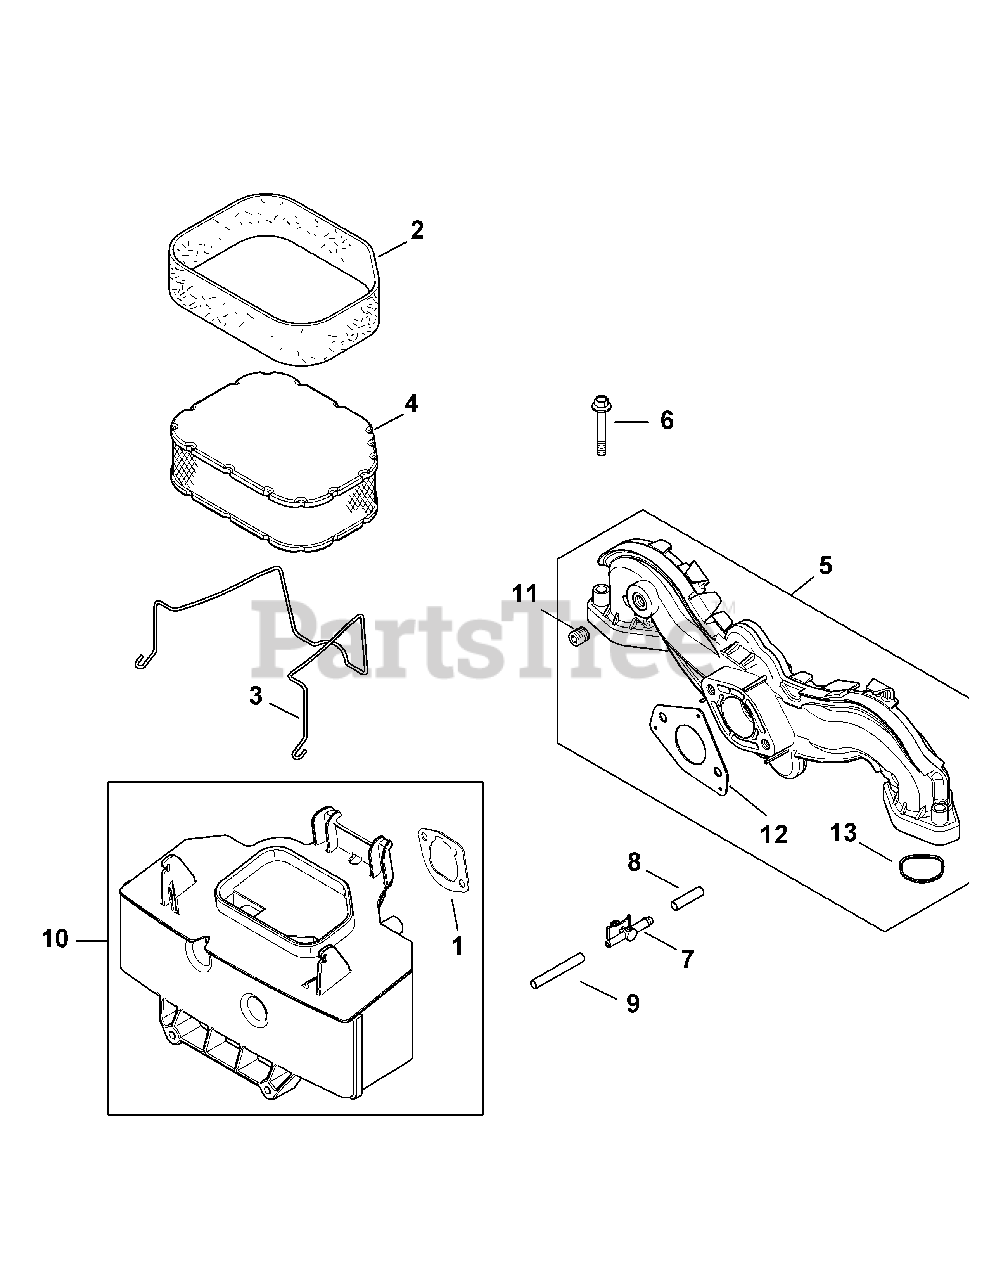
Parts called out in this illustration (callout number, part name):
1	Air Cleaner Base Gasket
2	Pre-Cleaner Element
3	Air Cleaner Element Latch
4	Air Filter & Pre-Cleaner Elements
5	Intake Manifold Kit
6	Flange Screw, M6 x 1.0 x 40
7	Evaporative Connector
8	Evaporative Mask
9	Evaporative Hose, 20"
10	Air Cleaner Base
11	Pipe Plug, 1/8
12	Intake Port O-Ring
13	Carburetor Gasket
